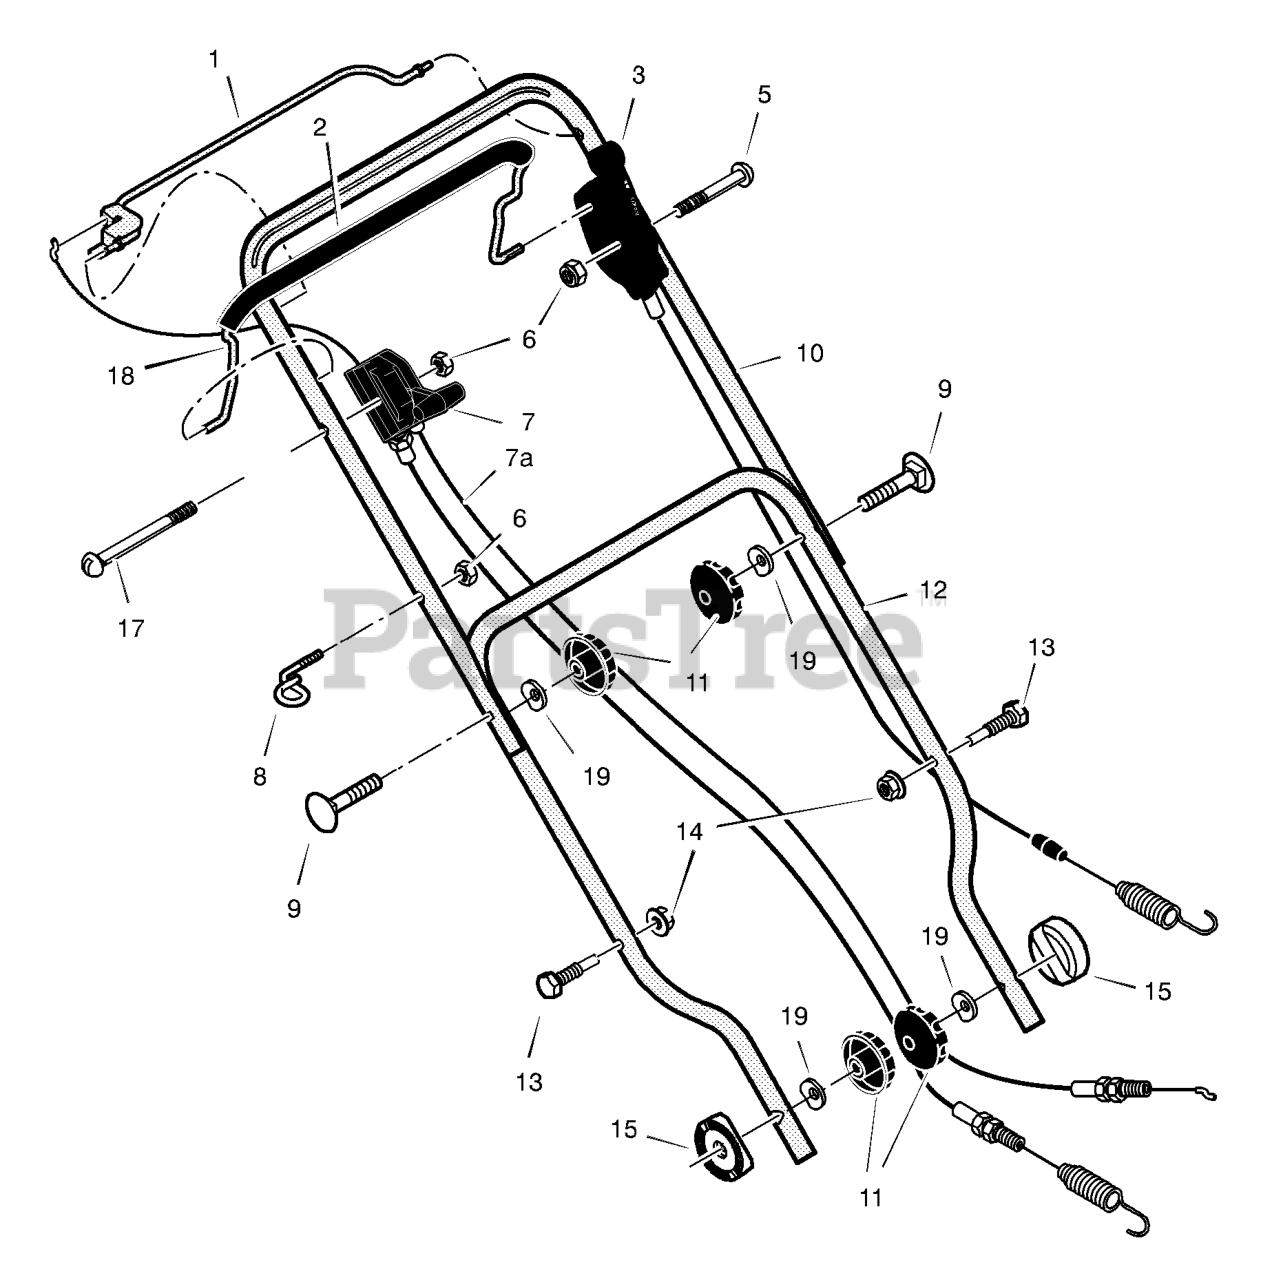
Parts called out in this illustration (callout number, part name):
1	Lever, Drive
2	Cover, Stop Lever
3	Control, Blade Drive
6	Nut
7	Cable, Control -Speed Selector &
7A	Cable, Drive
8	Guide, Rope
9	Bolt, Carriage
10	Handle, Upper
11	Knob, Handle
12	Handle, Lower
13	Bolt, Handle Support
14	Nut, Flange
15	Adjuster, Handle
17	Bolt, Hex
18	Lever, Bail Stop
19	Washer, Formed
